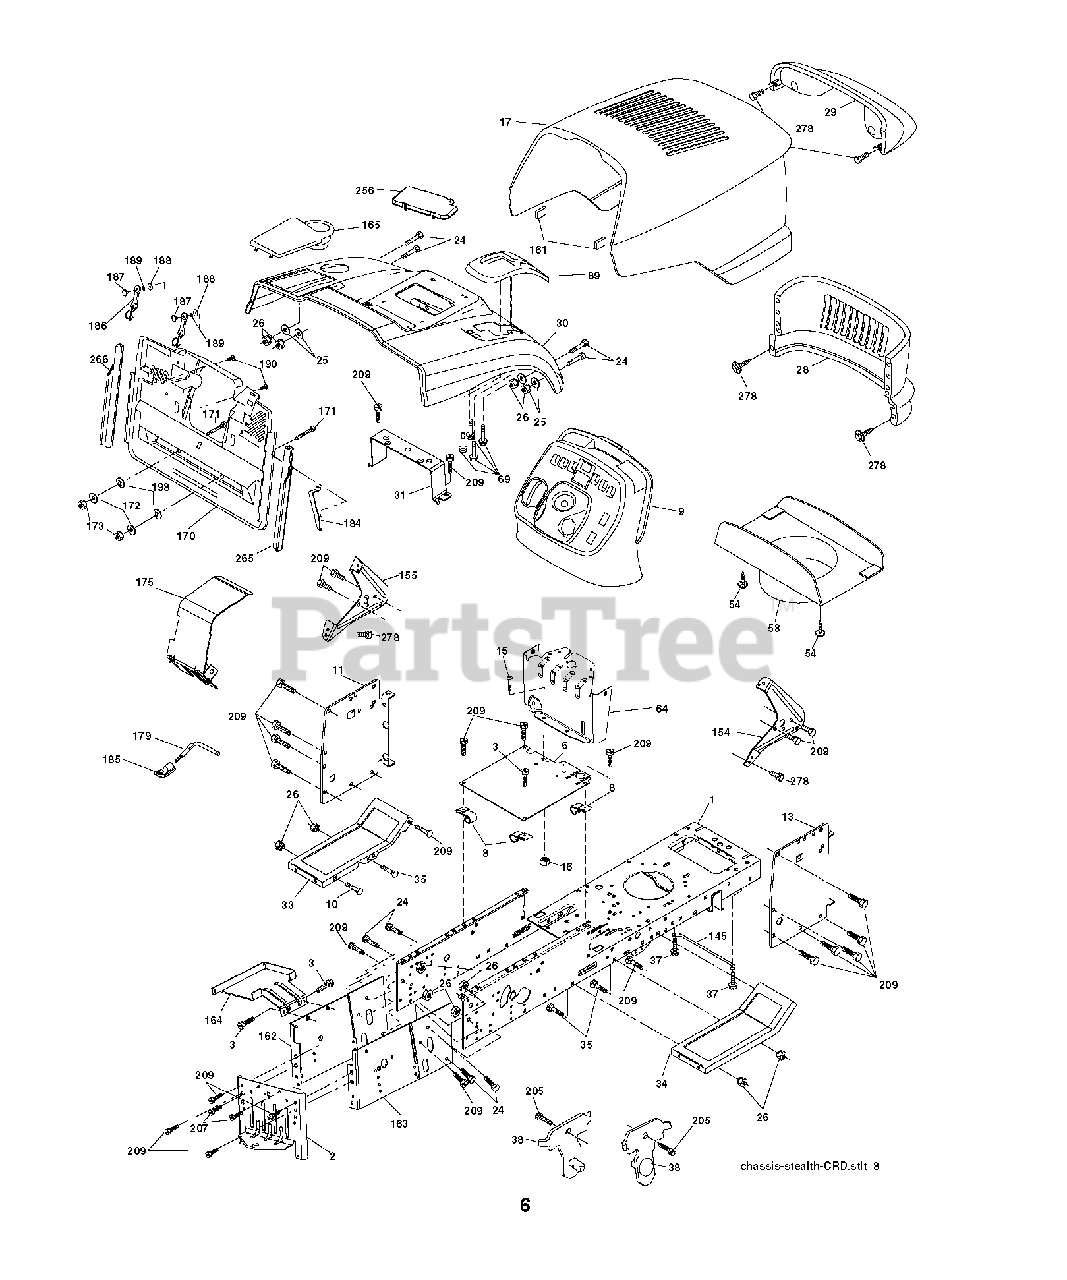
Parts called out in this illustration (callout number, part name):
1	CHASSIS
3	SCREW 3/8-16X3/4
8	CLIP,INSULATOR
10	BOLT D
13	PANEL DASH RH
16	NUT
25	WASHER
26	NUT
31	BRACKET SUPPORT FENDER
54	SCREW.WSHD.HEX10-32X5/8
58	DUCT HOOD
69	SCREW.HI-LO.CONSOLE
145	ROD.PIVOT.HOOD
161	EXTRUSION BUMPER
164	SUPPORT
171	BOLT
172	WASHER
186	LATCH ASSY
187	WELDNUT
189	LOCKWASHER
207	SCREW, 5/16-18 X 1/2
209	SCREW, 3/8-16X3/4
278	SCREW
